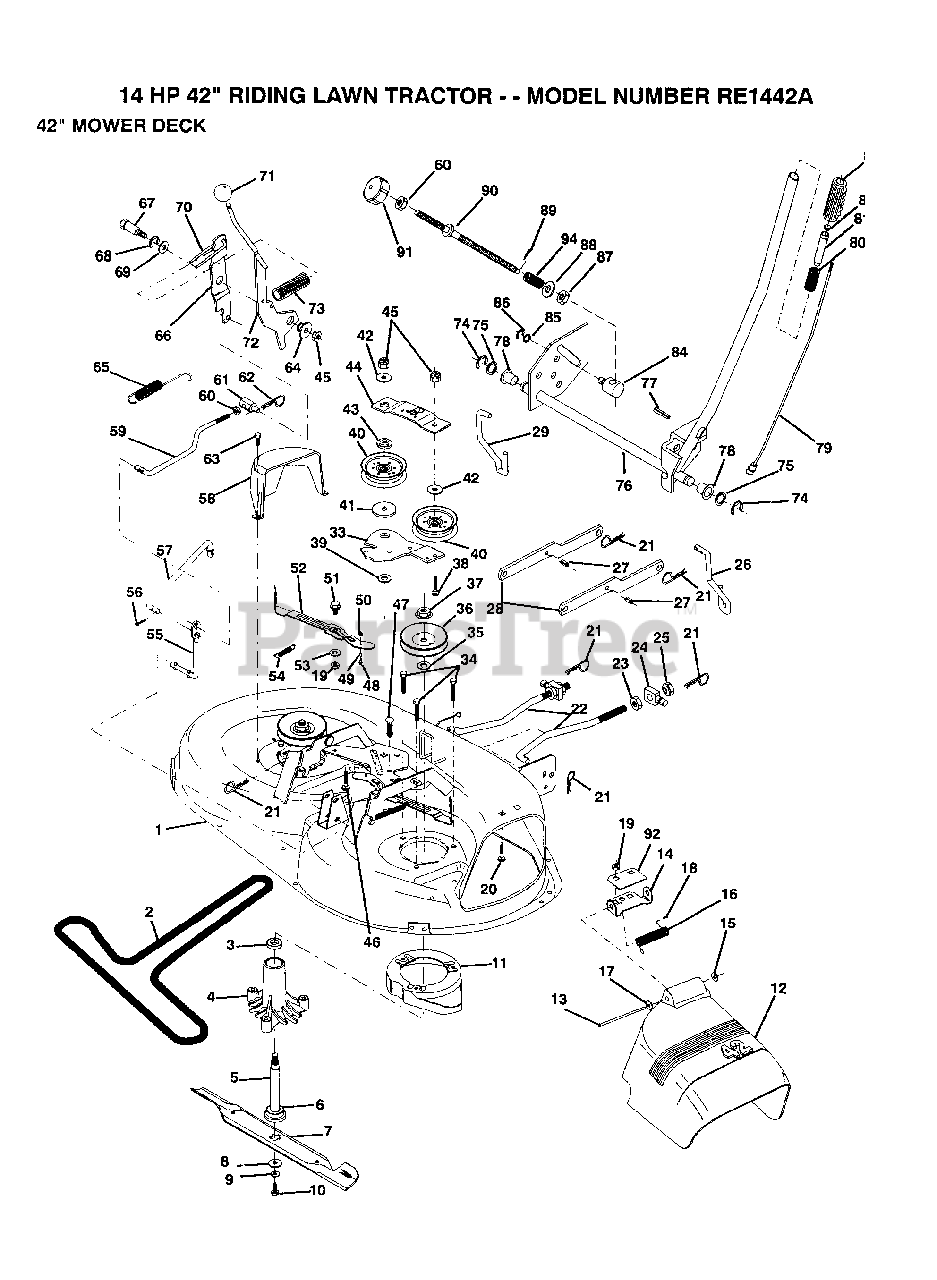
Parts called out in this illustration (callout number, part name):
2	BELT-V.92.4.MWR
3	BEARING
4	HSG ASM MANDREL
6	BEARING.BALL
8	WASHER BLADE
10	BLADE BOLT
12	DEFLECTOR.SHIELD
13	HINGE ROD
14	DEFLECTOR BRKT
15	NUT PUSH M
16	SPRING TORSION
17	WASHER
18	CAP-SLEEVE LT
20	BOLT
22	LINK.FRONT
23	NUT
24	TRUNION
25	NUT.LK.W/WSH.1/2.
26	LIFT LINK RH
27	"PIN,SPRING"
28	SUSP ARM ASM REAR
29	LINK LIFT LH
33	IDLER ARM
35	WASHER
38	BOLT
39	HARDENED WASHER
40	FLAT IDLER PULLEY
41	SPACER RETAINER
42	WASHER GT
43	RETAINER SPACER
44	IDLER ARM STIFF
46	BOLT CARRIAGE
47	XMAS TREE FASTNER
48	SHOULDER BOLT
50	LOCKNUT
52	BRAKE PAD ARM ASM
53	HARD SMALL WASHER
54	SPRING EXTENSION
55	PIVOT ROD
57	CLUTCH ROD SECOND
60	NUT
61	TRUNION
62	RETAINER M
63	SCREW LT
64	BUSHING
65	RETURN SPRING
66	CLUTCH ARM SECOND
67	SHOULDER BOLT
68	RING
69	WASHER
70	SPRING KEEPER
71	KNOB T(3/8 HOLE)
72	CLUTCH ARM PRI AS
75	WASHER
77	PIN-GROOVE LT
78	NYLON BEARING
83	GRIP
84	TRUNION LT
85	WASHER
86	KLIP RING
87	NUT T
88	WASHER
92	STIFFENER BRKT
94	SPRING T
